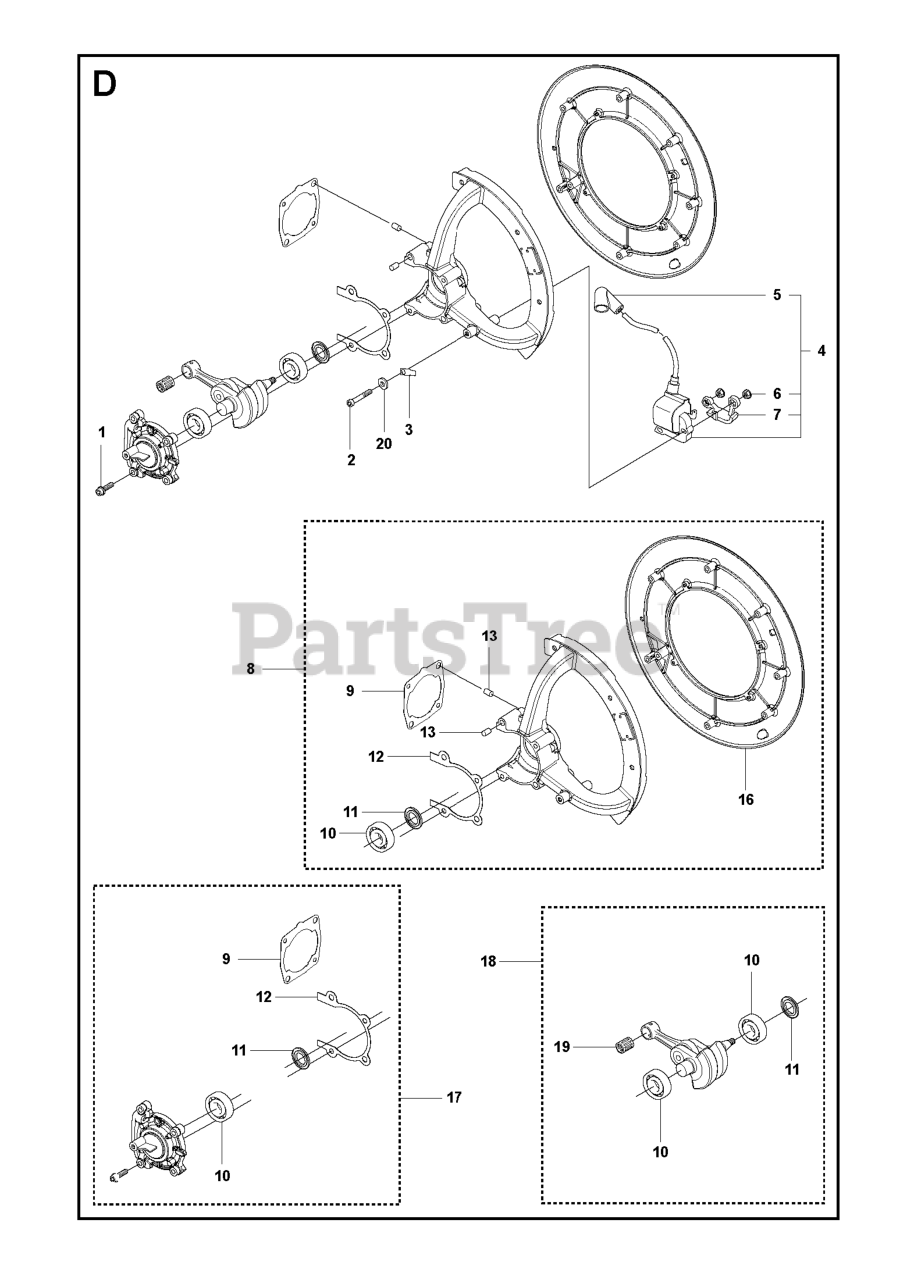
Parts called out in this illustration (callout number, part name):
1	SCREW
3	FLAT PIN
5	SPARK PLUG CONN. KIT
8	CRANKCASE KIT
10	BALL BEARING-6202-C3 SKF
13	SLEEVE
18	CRANKSHAFT
19	BEARING
20	WASHER 4.2X9
